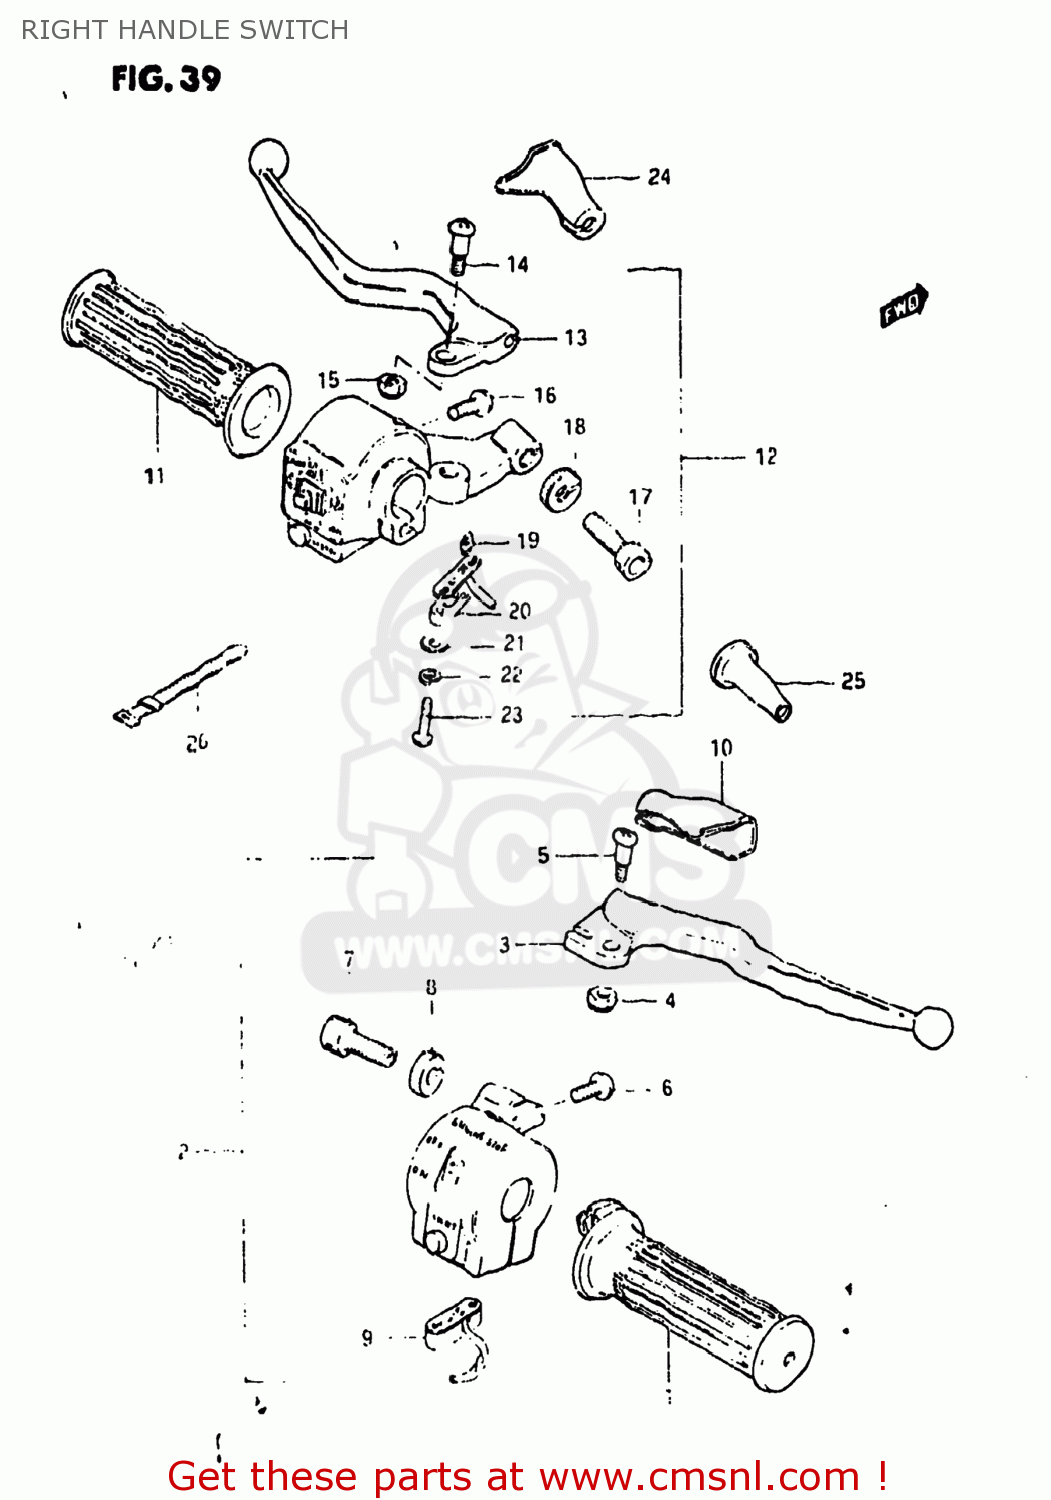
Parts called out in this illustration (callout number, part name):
1	GRIP,THROTTLE
2	LEVER/SWITCH ASSEMBLY,BRAKE
3	LEVER,BRAKE
4	NUT,LEVER BOLT
5	SCREW
6	SCREW 5X20
7	ADJUSTER,CABLE
8	NUT,CABLE ADJUSTER
9	SWITCH ASSEMBLY
10	COVER,BRAKE LEVER DUST
11	GRIP,L
12	LEVER ASSEMBLY,CLUTCH
13	LEVER,CLUTCH
14	SCREW
15	NUT,LEVER BOLT
16	SCREW 5X20
17	ADJUSTER,CABLE
18	NUT,CABLE ADJUSTER
19	CONTACT,SWITCH
20	COVER,FR BK TERMINAL BASE
21	WASHER
22	LOCK WASHER
23	SCREW
24	COVER,CLUTCH LEVER
25	BOOT,CLUTCH CABLE
26	CLAMP(L:120)
